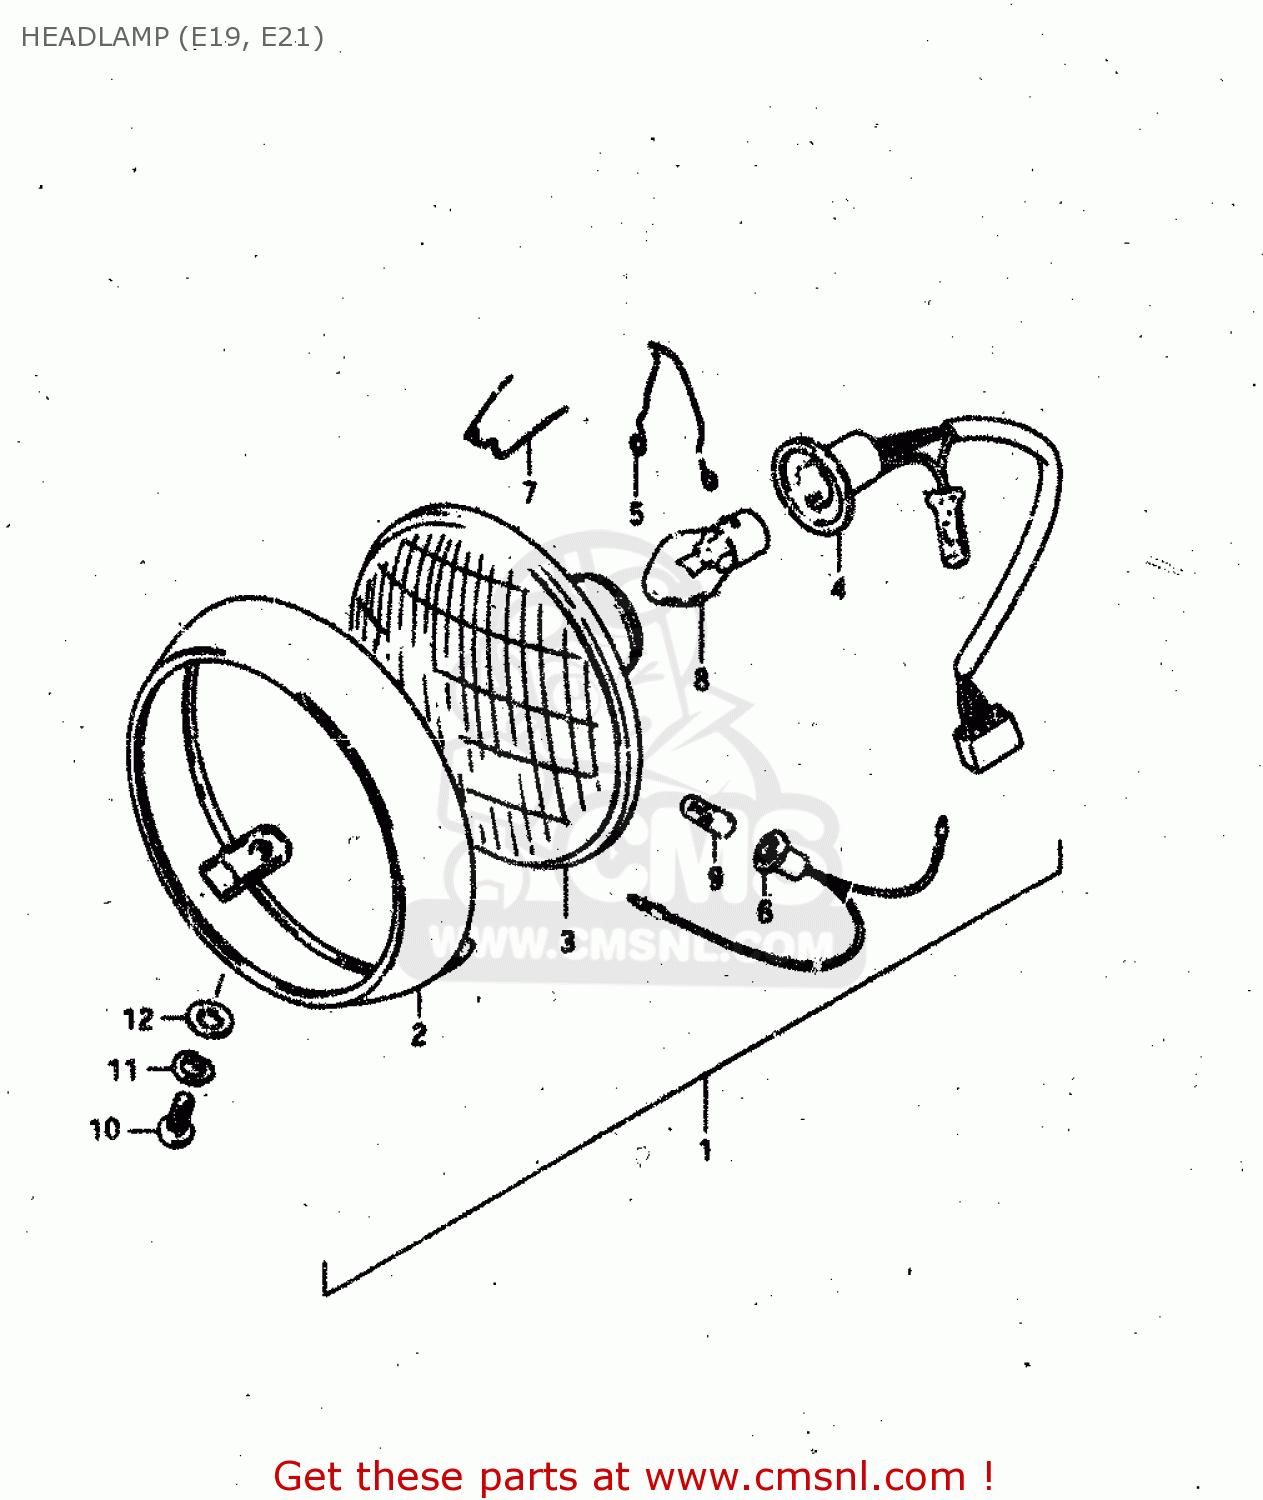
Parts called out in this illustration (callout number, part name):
1	HEADLAMP ASSY
2	RIM
3	UNIT
4	SOCKET
5	CLAMP,HEADLAMP
6	SOCKET
7	SPRING
8	BULB (6V,15/15W)
9	BULB (6V,4W)
10	SCREW
11	LOCK WASHER
12	WASHER
